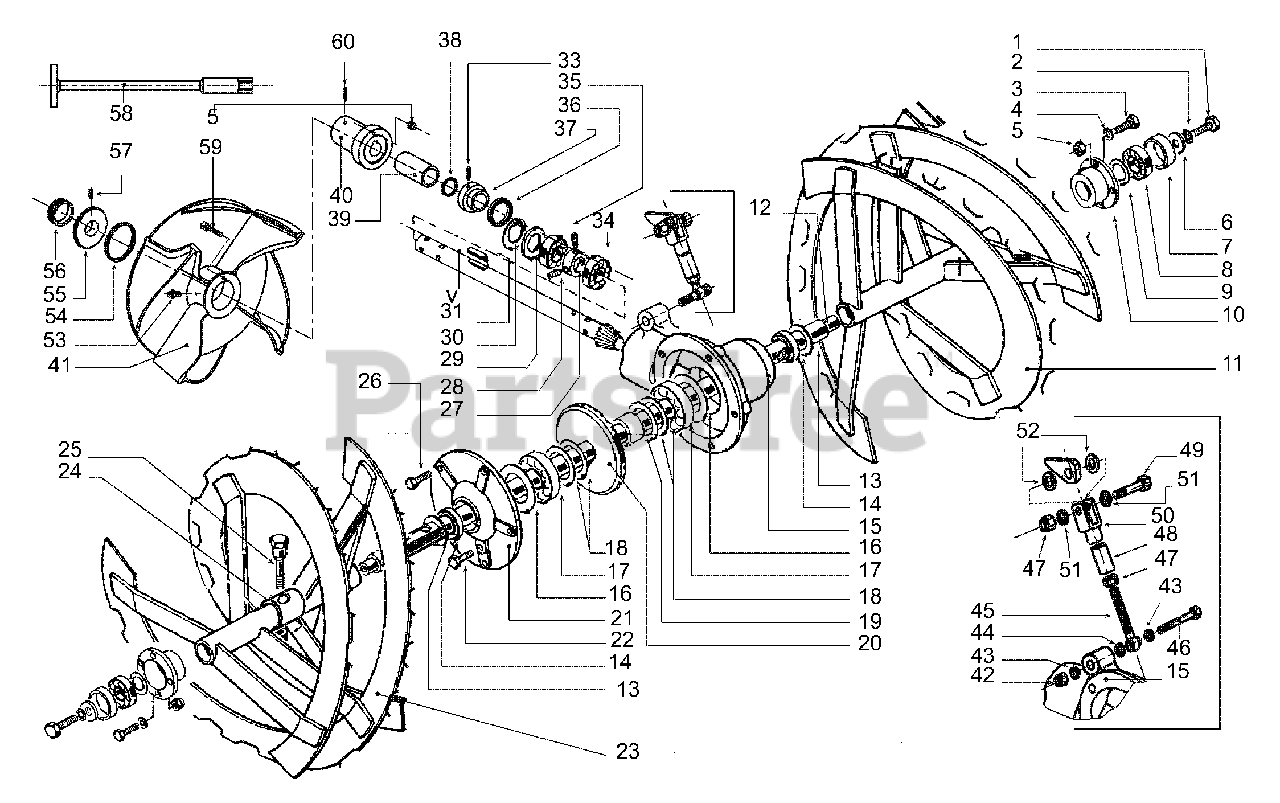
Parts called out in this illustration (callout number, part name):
1	Hexagonal Head Screw M8 x 25 - Din 933
2	Inner Denticulated Washer M8 - Din 6798j
3	Hexagonal Head Screw M6 x 20 - Din 933
4	Washer 6.6 x 18 x 2 - UNI 6593
5	Self Locking Nut M6 - Din 982
6	Washer 8.5 x 28 x 5
7	Distance Ring 41 x 46.5 x 13
8	Bearing 6204 2RS 20 x 47 x 14
9	Ring 20.3 x 37.5 x 0.3
10	Support For Auger Shaft
11	Right Auger
12	Auger Shaft
13	Washer 30.3 x 45x2
14	Oil Seal 30 x 45 x 8
15	Gear Box
16	Ring 40 x 61.5 x 1
17	Bearing 62046 ZZ - 30 x 62 x 16
18	Ring 30.5 x 50 x 0.2
19	Distance Ring 30 x 40 x 25
20	Gear Wheel
21	Gear Box Cover
22	Hexagonal head screw M8 x 16 - DIN 933
23	Left auger
24	Self Locking Nut M6 - Din 982
25	Safety Bolt For Auger
26	Hexagonal Head Screw M8 x 35 - Din 933
27	Fastening Ring 25 x 37 x 15
28	Grub - Screw M8 x 8 - Din 914-45h
29	Distance Ring 38 x 51.8 x 3.3
30	Snap Ring Ø52 - Din 472-1
31	Key 8 x 7 x 30
33	Grub - Screw M8 x 10
34	Bearing 3205 2rs - 25 x 52 x 20.6
35	Bearing 6205 2rs - 25 x 52 x 15
36	Oil Seal 35 x 52 x 7
37	Guard Ring For Oil Seal
38	O-ring 132
39	Spacing Bar
41	Second Stage Impeller (Ø 370 mm. Left Hand, 3 Buckets)
42	Self Locking Nut M10 - Din 985
43	Washer Ø 10.5 x 21 x 2 - Din 125a
44	Washer Ø 10.5 x 21 x 1
45	Eye Tie Rod M12 x 95 - Hole Ø 10
46	Hexagonal Head Screw M10 x 53
47	Self Locking Nut M12 - Din 985
48	Spacer Ø 12.4 x 20 x 38
49	Hexagonal Head Screw M12 x 43
50	Clevis M12
51	Washer Ø 13 x 24 x 2,5
52	Washer Ø 13 x 28 x 1
53	Grease Nipple M8
55	Distance Ring
56	V. Ring A 38
57	Grub-Screw M8 x 6 - Uni 5923
58	Hexagonal Socket Wrench (10mm)
59	Hexagonal Head Screw M6 x 35 - Din 931
60	Grub-screw M12-1.25 x 9
